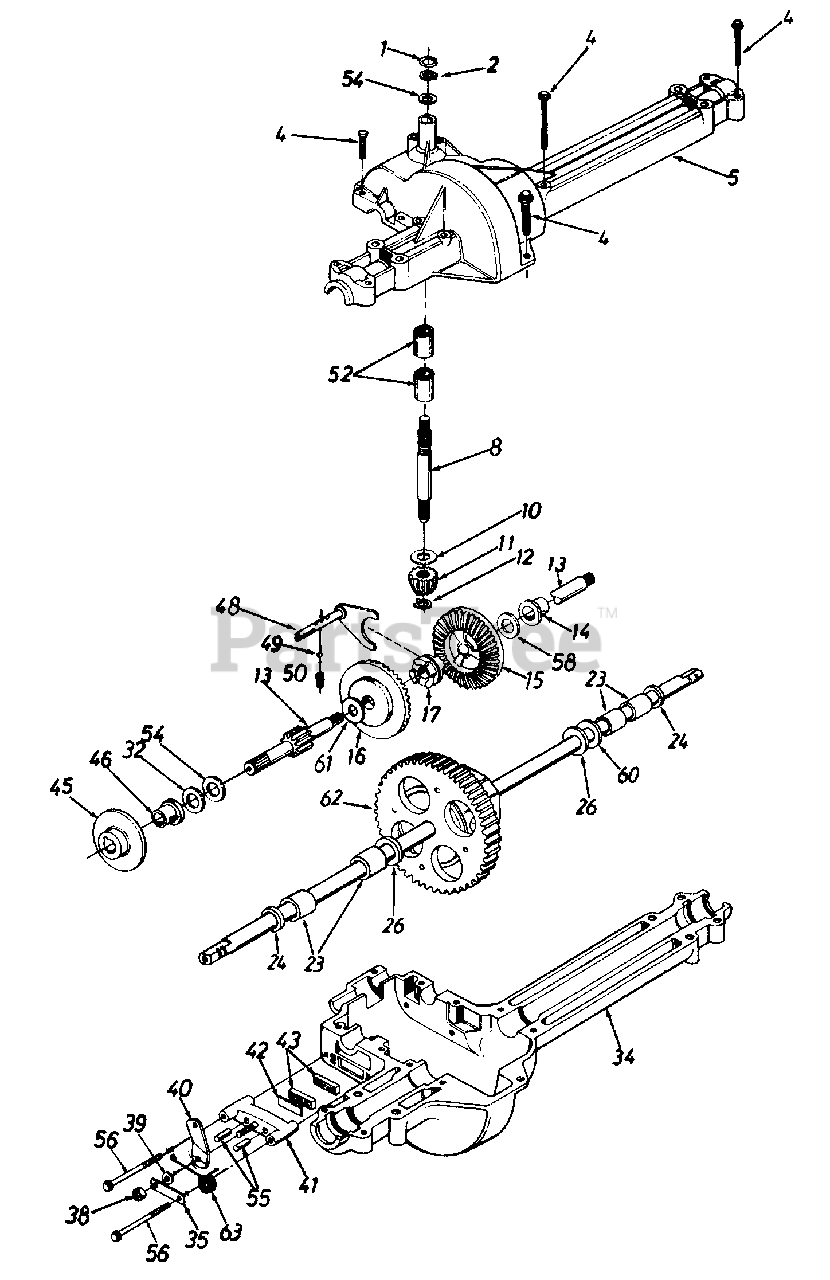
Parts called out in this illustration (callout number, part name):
1	Wire Ring
2	Retaining Ring
4	Scritt 1/4-20 x 1.625
5	Upper Housing
8	Input Shaft
10	Thrust Washer 5/8" I.D. x 1.25" Lg.
11	Pinion Input 14T
12	Retaining Ring
13	Drive Shaft L.H. Brake
14	Flange Brg. 5/8" I.D. x 3/4" Lg.
15	Bevel Gear 42T Small I.D.
16	Bevel Gear 42T Large I.D.
17	Clutch Collar
23	Sleeve Bearing 3/4" I.D. x 1.0"
24	Oil Seal 3/4" I.D.
26	Flat Washer .760" I.D. x 1.5" O.D.
32	Thrust Washer 5/8" x 1" x .025"
34	Lower Housing
35	Anti-Rotation Brkt.
38	Hex Nut 5/16-24 Thd.
39	Flat Washer .344" I.D. x .875" O.D.
40	Actuating Arm
41	Brake Yoke
42	Puck Plate
43	Brake Puck
45	Brake Disc
46	Flange Bearing 5/8" I.D. x 15/16"
48	Shift Fork Ass'y.
49	Ball Detent .250" Dia.
50	Spring Detent
52	Needle Brg. 5/8" I.D, x 1/2" Lg.
54	Flat Washer 5/8" I.D. x 1" O.D.
55	Actuating Pin 5/16" Dia.
56	Hex Wash Hd. Self-Tap Scr.
58	Flat Washer 5/8" I.D. x 1" O.D.
60	Flat Washer .76" x 1.5" x .010"
61	Thrust Washer
62	Differential Ass'y.
63	L.H. Brake Spring
